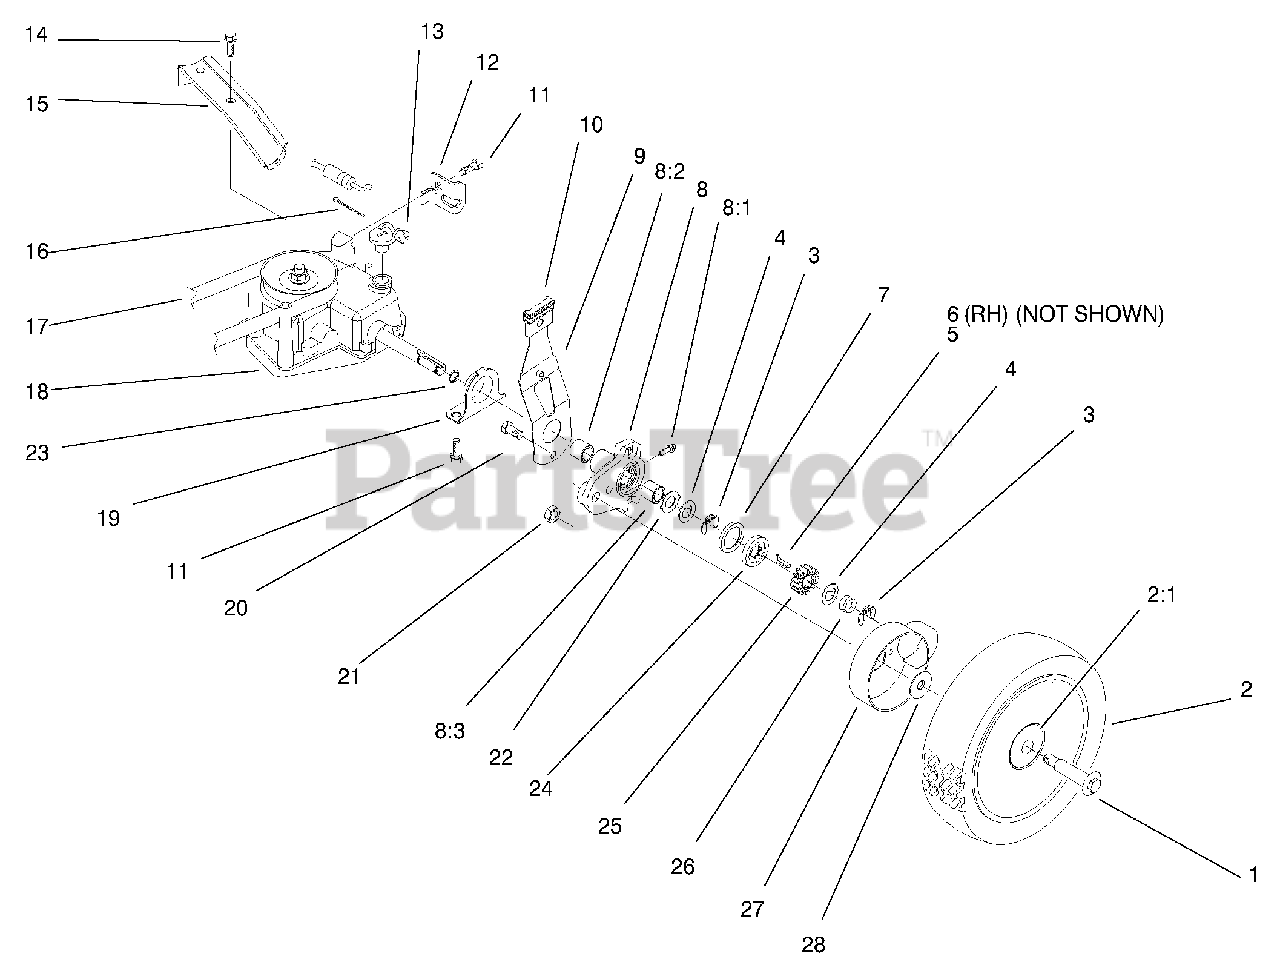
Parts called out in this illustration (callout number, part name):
1	Bolt-Shoulder
2	Wheel ASM
3	Ring-Klip
4	Washer-Thrust, Keyed
5	Key-Rocking, LH
6	Key-Rocking, RH
7	Ring-Friction
8	Pivot Arm Assembly
8:1	Fitting-Zerk
9	Spring Arm ASM
10	Knob-Arm
12	Cable Retainer
13	Shift Lever
14	Screw-Taptite
15	Bracket-Guide, Belt
16	Pin-Cotter
18	Gearcase Assembly
22	Washer-Arm, Pivot
24	Washer-Clutch
25	Gear-Pinion
26	Spring-Compression
27	Cover-Wheel
28	Spacer-Cover, Wheel
